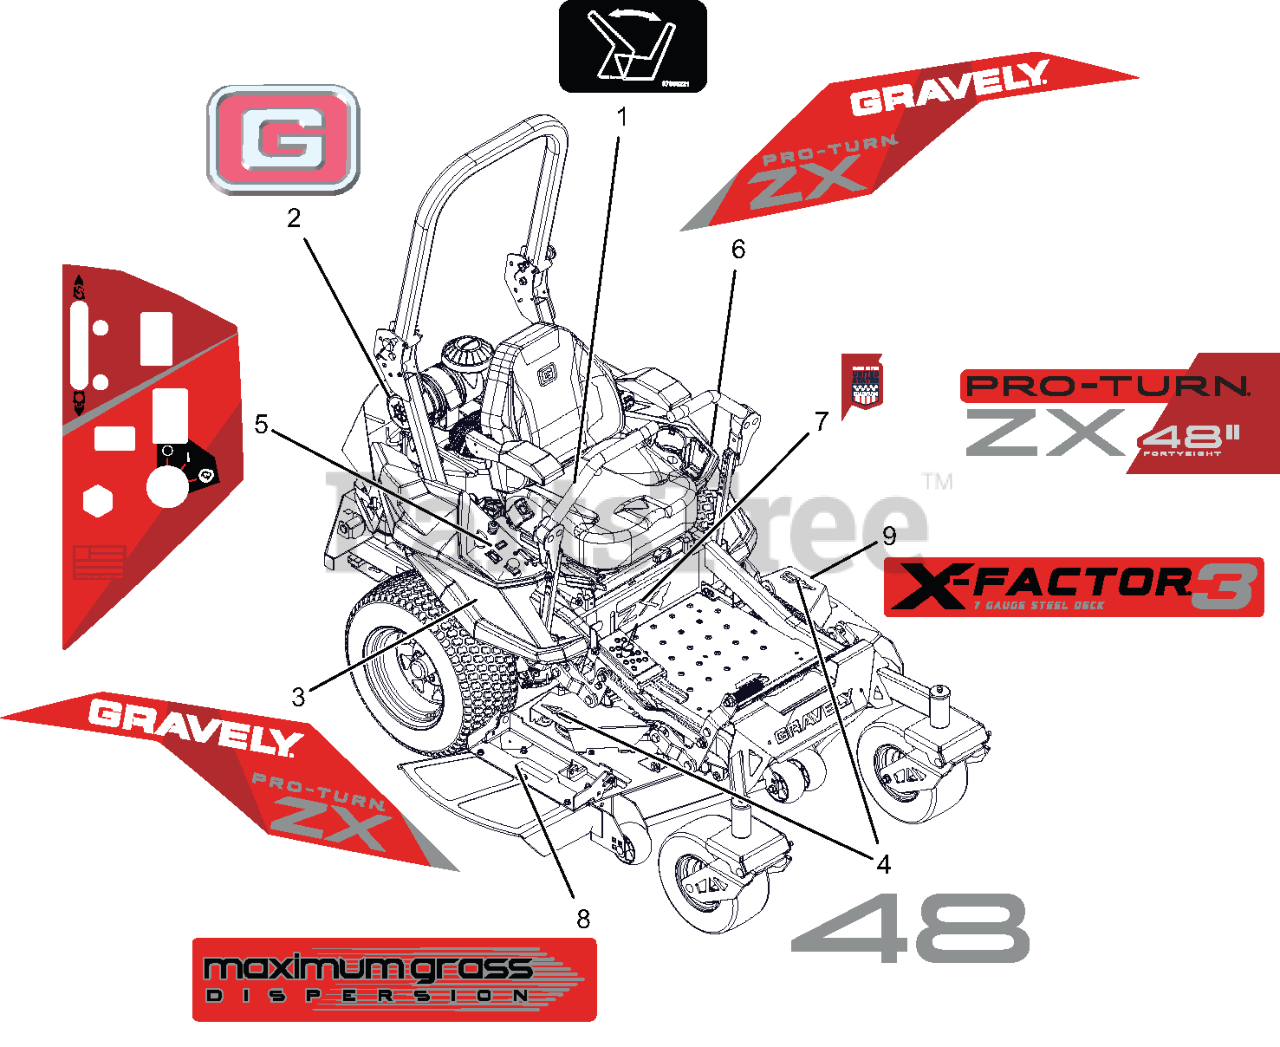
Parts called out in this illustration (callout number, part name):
1	DECAL - SEAT RELEASE
2	DECAL, GRAVELY BRAND
3	DECAL, FENDER RH - PTZX
4	DECAL, DECK - 48
5	DECAL, CONTROL PANEL
6	DECAL, FENDER LH - PTZX
7	DECAL, PTZX -48
8	DECAL, DECK - MAX GRASS
9	DECAL, DECK - X-FACTOR 3 7 GAUGE
